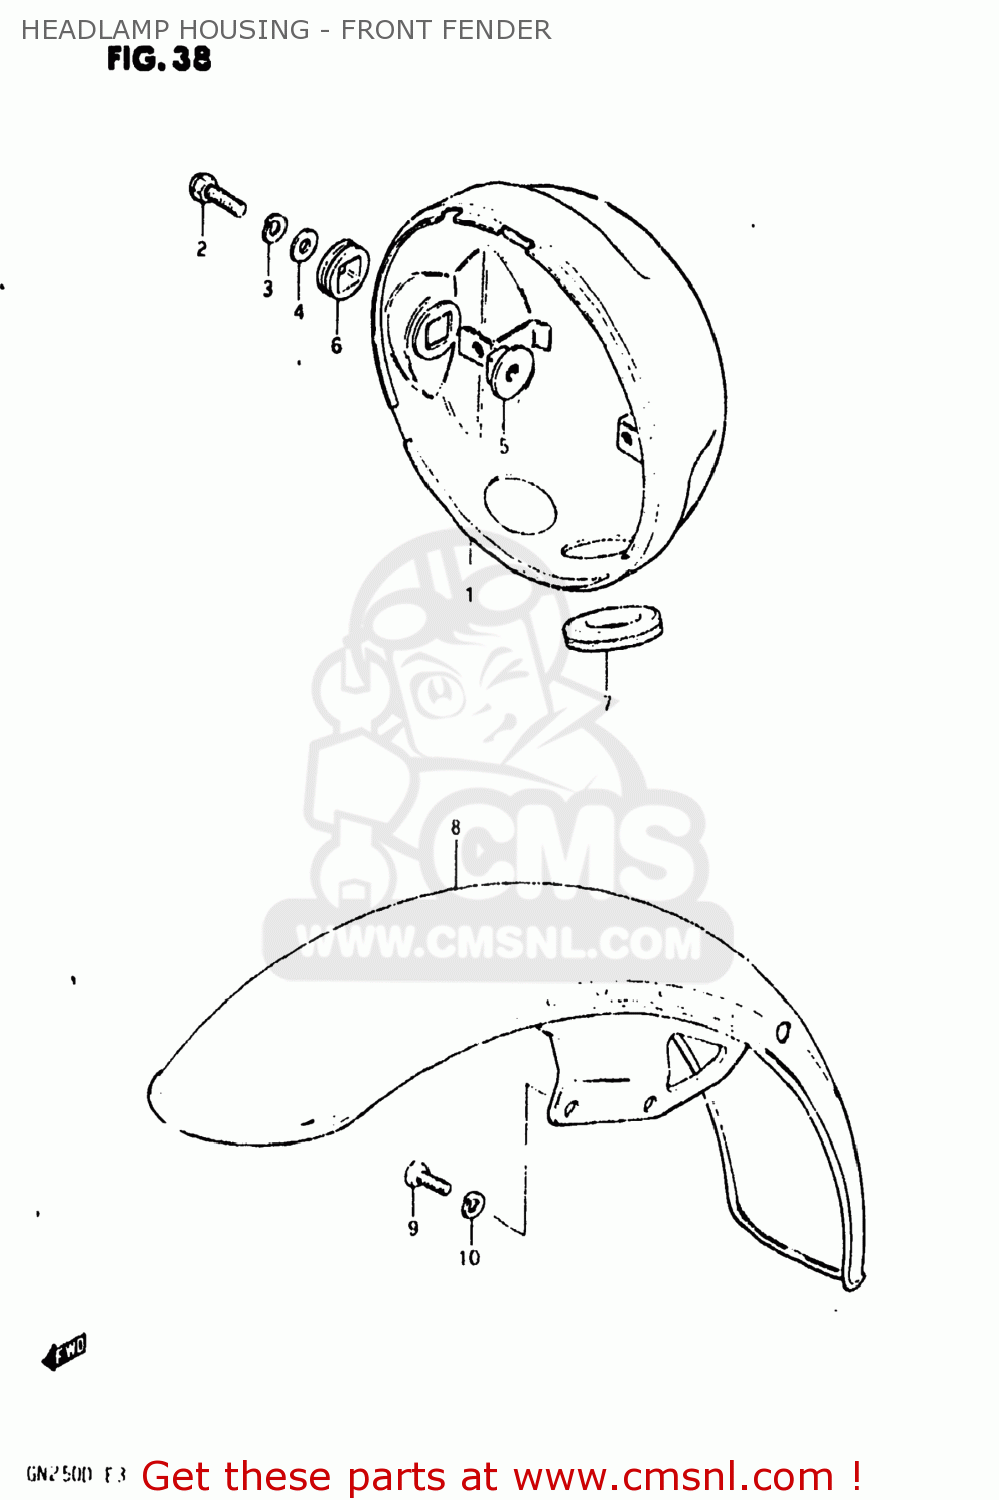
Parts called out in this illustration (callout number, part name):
1	HOUSING,HEADLAMP
2	BOLT
3	LOCK WASHER
4	WASHER
5	SPACER,HEADLAMP HOUSING
6	CUSHION,HEADLAMP HOUSING
7	GROMMET,HEADLAMP HOUSING
8	FENDER,FR
9	BOLT
10	LOCK WASHER
